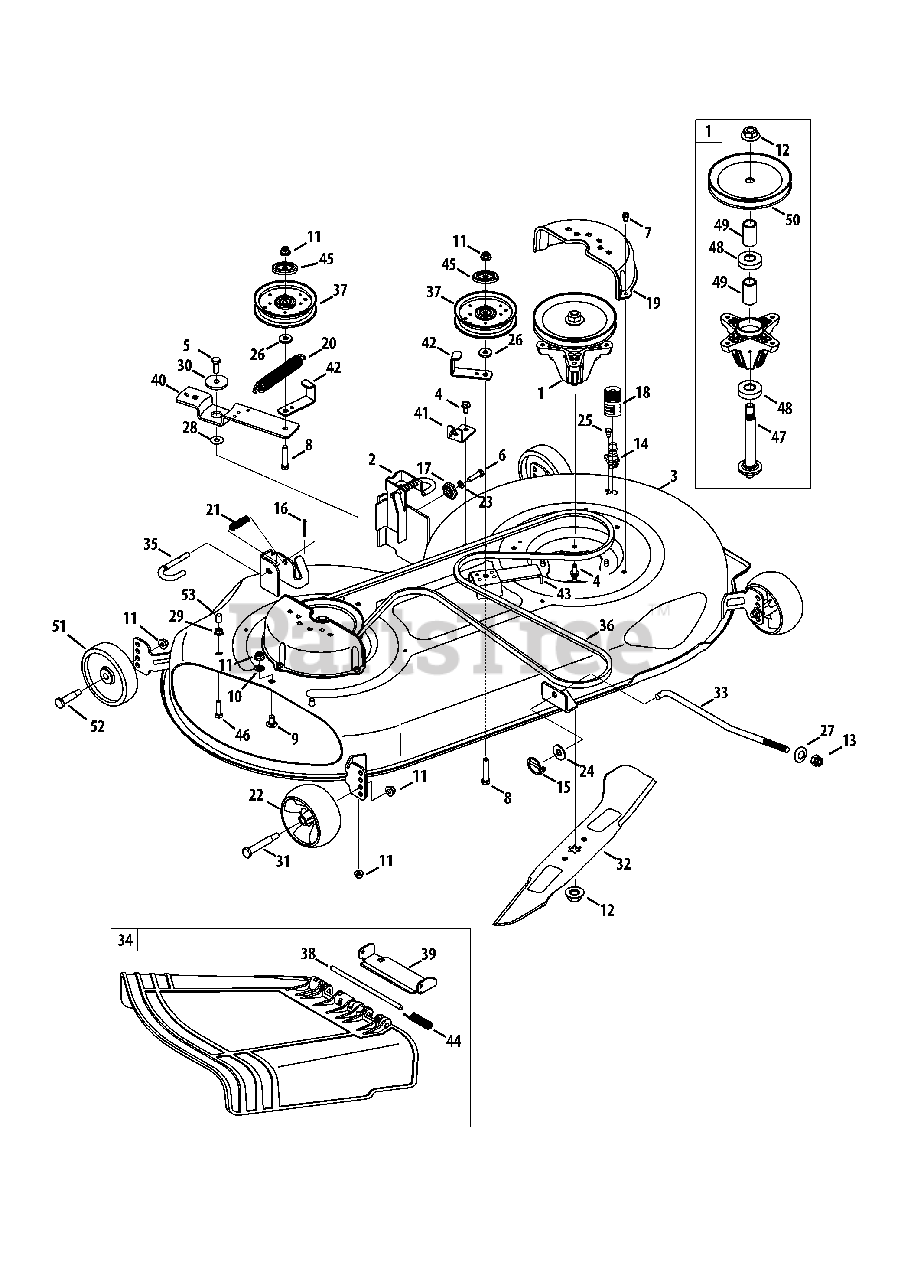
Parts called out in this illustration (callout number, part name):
1	Spindle Assembly, Pulley 6.93 Dia.
2	Bracket Assembly, Deck, Hanger LH
3	Deck, Offset, 46"
4	Screw, Self-tapping, 5/16-18, .750,
5	Hex Screw, 3/8-16, 1.00, Gr5, Std
6	Hex Screw, 5/16-18, 1.25, Gr5, Std
7	Screw, Self-tapping, 1/4-20, 0.500,
8	Hex Screw, 3/8-16, 2.00, Gr5, Std
9	Bolt, Carriage, 3/8-16, 0.75, Gr1
10	Nut, Push, 3/8
11	Nut, Flange Lock, 3/8-16, Nylon
12	Nut, Flange, 5/8-18
13	Nut, 1/2-13
14	Deck Wash Nozzle
15	Pin, Lynch, .1875
16	Pin, Cotter, 1/8 X 1.25
17	Gear, Deck, Adj
18	Adapter, Water
19	Cover, Belt, Universal
20	Spring, Extension, .94 Dia. X 6.74
21	Spring, Compression, .535 OD X 1.75
22	Wheel, Deck, 5.0 Dia. Ball
23	Washer, Lock, 5/16, Regular Duty
24	Washer, Flat, .531 X 1.25 X .100
25	Shoulder Screw, 1/4-20 x 0.50
26	Washer, Flat, .385 X .870 X .092
27	Washer, Bell, .63 X 1.25 X .18
28	Washer, Flat, .385 X 1.0 X .030
29	Nut, Flange Lock, 5/16-18, Grf
30	Spacer, Shoulder, .8840 X .190
31	Bolt, Shoulder, .496 X 2.50, 3/8-16
32	Blade, Cut, 23.25" 2-In-1, Cub
33	Rod, Lift, Deck, Front, 13.7
34	Chute Assembly, 46" Deck
35	Rod, Deck Release .375 Dia.
36	Belt, V-Type, A Sec
37	Pulley, Idler, 4.25" Dia.
38	Pin, Hinge, 7.96
39	Bracket, Chute
40	Bracket, Idler, Pivot
41	Bracket, Cable, Deck Engage
42	Bracket, Guard, Belt, 4.25 Pulley
43	Bracket, Support, Stationary Idler
44	Spring, Torsion, .44 I.D. X 2.0
45	Pulley Cap
46	Hex Cap Screw, 5/16-18 x 1.00
47	Shaft, Spindle, 6.11
48	Bearing, Ball, .787 X 1.85 x.551
49	Spacer, .792 X 1.060 X 1.860
50	Pulley, Deck, 6.93 Dia.
51	Wheel, Deck 5.0 x 1.38
52	Bolt, Shoulder, .496 x 1.525, 3/8-16
53	Cap, .290 x .500
